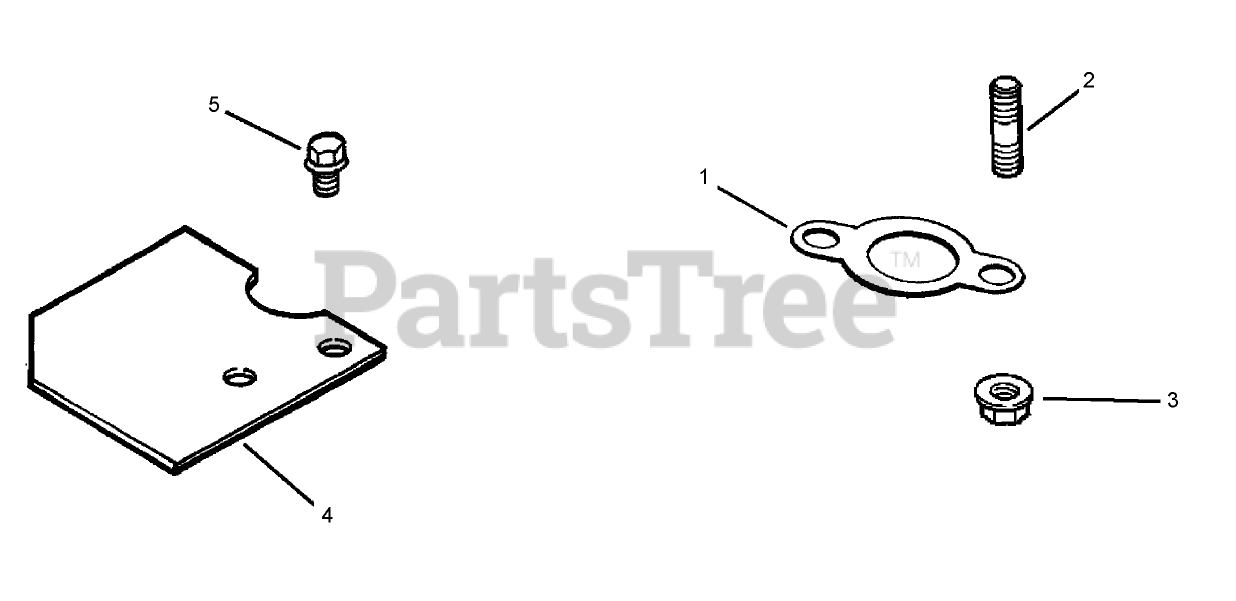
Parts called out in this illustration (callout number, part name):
1	GASKET-EXHAUST
2	STUD (M8X1.25X33)
3	NUT-FLANGE (M8X1.25)
4	Deflector, heat
5	SCREW-FLANGE, THREAD FORMING (M6X1.0X16)
